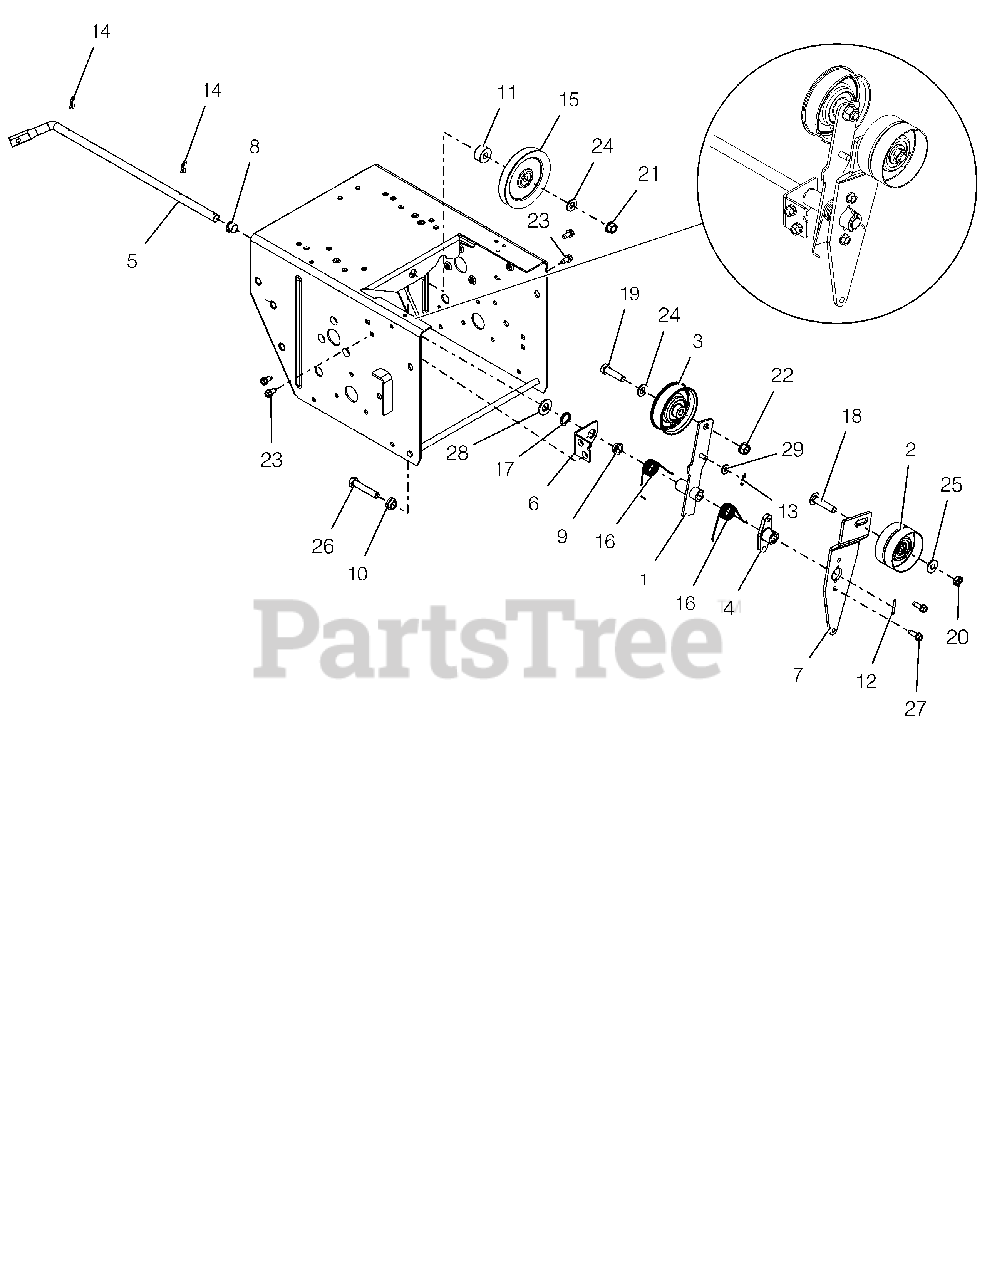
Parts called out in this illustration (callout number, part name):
1	ARM, TRACTION CLUTCH
2	IDLER, FLAT-2.75 OD X .375 ID
3	IDLER, FLAT - 3.05" X .75"
4	HUB, BRAKE ARM
5	ARM, ATTACHMENT
6	BRACKET, SUPPORT
7	ARM, IDLER-ATTACHMENT
8	BUSHING, POLYLINER-.50 SPLIT
9	BSHG,FLANGE .500X.625X.270X.75
10	BSHG, FLANGE .391X.56X.313X.75
11	BSHG,POCKET .391X.570X1.0X.450
12	PIN-ROLL .125X1.00
13	PIN-HAIR INT .06X.18X.77
14	CLIP, SPRING
15	SHV, .38"ID X 4.00"OD V-IDLER
16	SG-TORS .067X.88
17	WAVE SPRING .600X.875X.25FH
18	BLT-RHDSSQNK .38-16X1.75 G5YZ
19	@BLT-HEX .38-16X1.50 GR5 YWZC
20	@NUT-LK-CTR-JAM .375-16 YWZC
21	@NUT-LK-TOP-FLG .38-16 YWZC
22	@NUT-LK-TOP-FLG .38-16 YWZC
23	SCR-TAP .25-20X.50 HWH TR YWZ
24	@WSHR-FL-STL.406X.812X.065 YWZ
25	@WSHR-FL-STL.38X.875X.083 YWZC
26	@BLT-HEX .38-16X2.00 GR5 YWZC
27	SCR-TAP-PM .25-20X.75 TR YWZ
28	@WSHR-FL-STL.531X1.06X.095YWZC
29	@WSHR-FL-STL.281X.62X.065 YWZC
